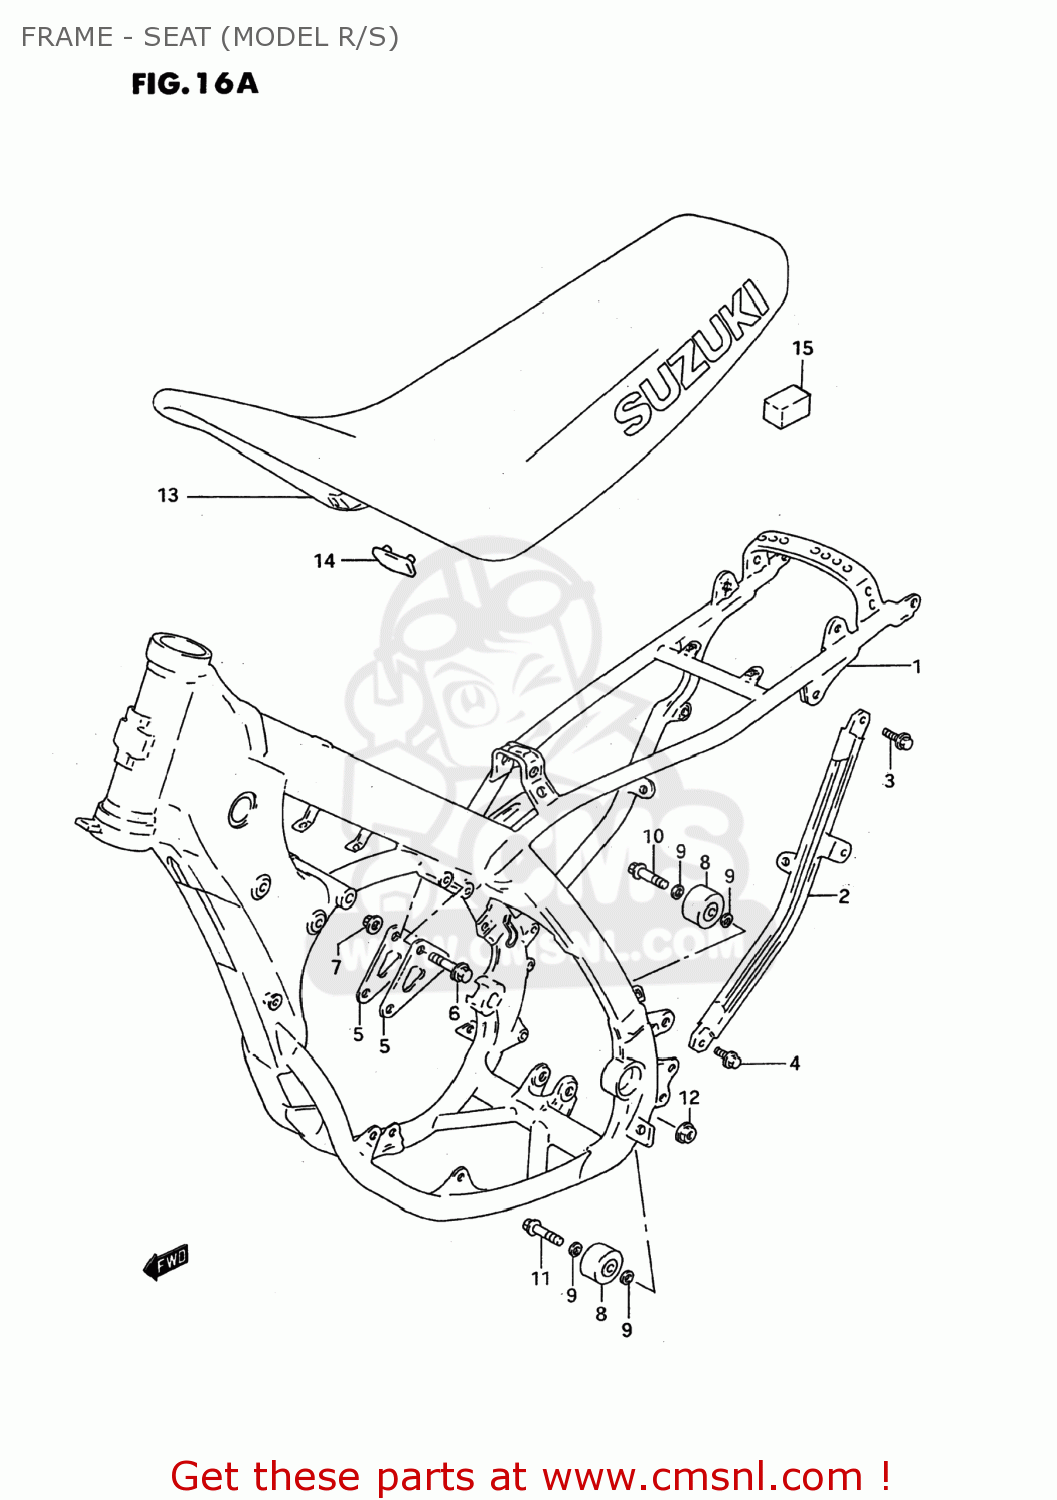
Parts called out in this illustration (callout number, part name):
1	FRAME
2	TUBE,FRAME SIDE,L
3	BOLT
4	BOLT, LOWER
5	PLATE,ENGINE MOUNT UPR
6	BOLT(8X41)
7	NUT
8	ROLLER,CHAIN
9	WASHER
10	BOLT(8X41)
11	BOLT(8X45)
12	NUT
13	SEAT SET
14	CUSHION
15	CUSHION,SEAT
